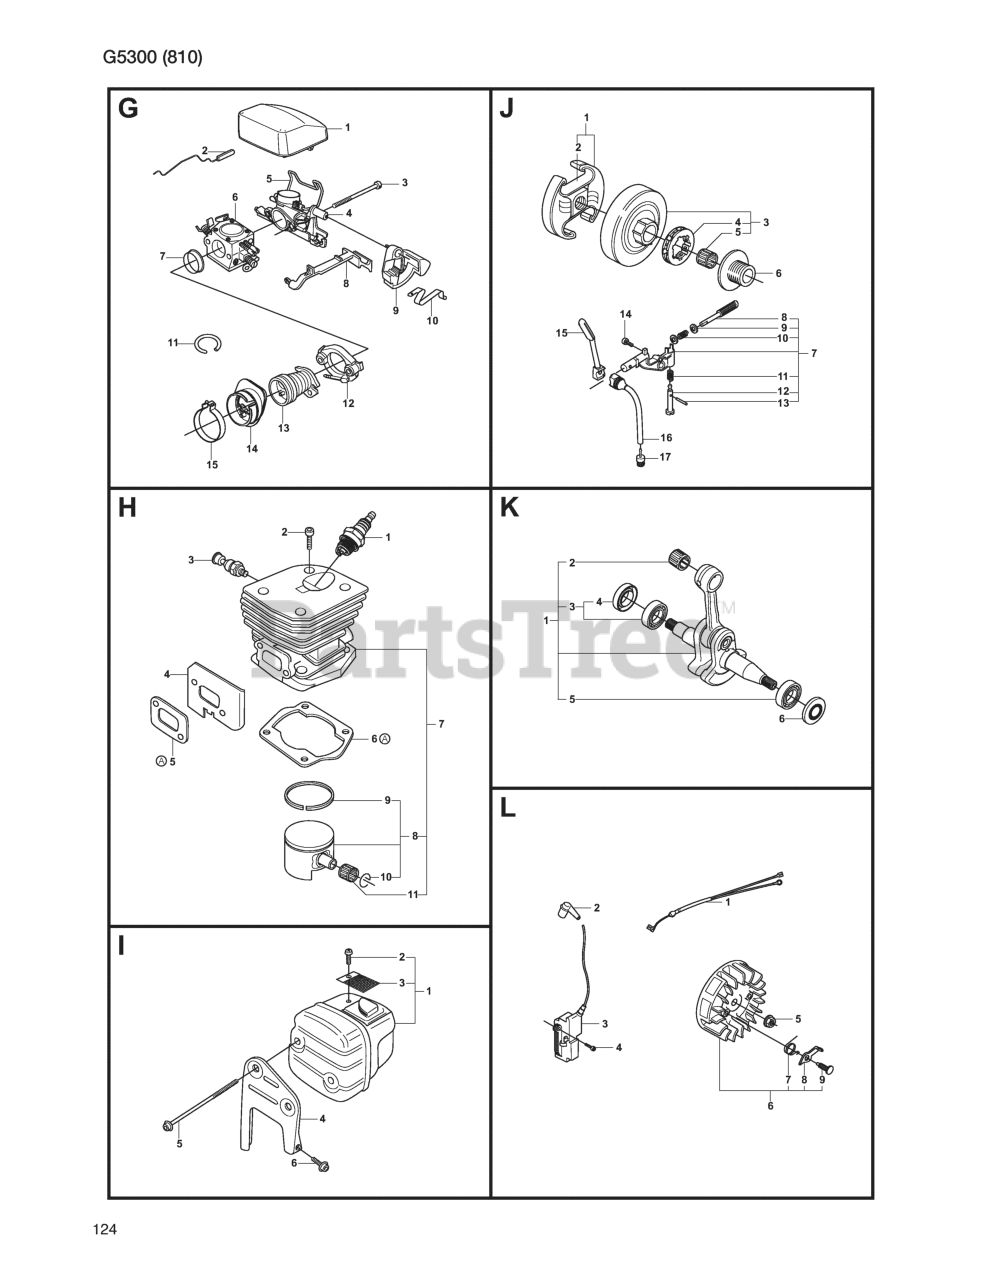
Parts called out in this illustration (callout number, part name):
G1	AIR FILTER
G2	THROTTLE WIRE ASSY
G4	INLET ELBOW
G6	CARBURETOR
G7	SUPPORT RING
G8	CHOKE CONTROL
G9	STOP CONTROL
G10	SHORT CIRCUIT SPRING
G14	INSULATION WALL
H1	SPARK PLUG
H2	SCREW IHSCM
H3	DECOMPRESSION VALVE
H4	HEAT DEFLECTOR
H7	CYLINDER ASSY
H8	PISTON ASSY
H9	PISTON RING
H11	NEEDLE BUSHING
A	GASKET KIT
I1	MUFFLER E-TECH
I2	SCREW CRPANM
I3	SPARK ARRESTOR SCREEN
J1	CLUTCH ASSY
J2	CLUTCH SPRING
J3	CLUTCH DRUM
J4	GEAR WHEEL
J5	NEEDLE BEARING
J6	PUMP PINION
J7	OIL PUMP ASSY
J8	PUMP PISTON
J9	WASHER STEEL
J12	ADJUSTER
J15	OIL PRESSURE HOSE
J16	OIL HOSE
J17	OIL PLUMMET
K1	SCREW IHSCT
K2	NEEDLE BUSHING
K3	BALL BEARING
K4	SEALING
K5	BALL BEARING
K6	SEALING RING
L1	WIRING ASSY
L2	SPARK PLUG CAP
L3	IGNITION MODULE
L6	FLYWHEEL
L7	SPRING
L8	STARTER PAWL
